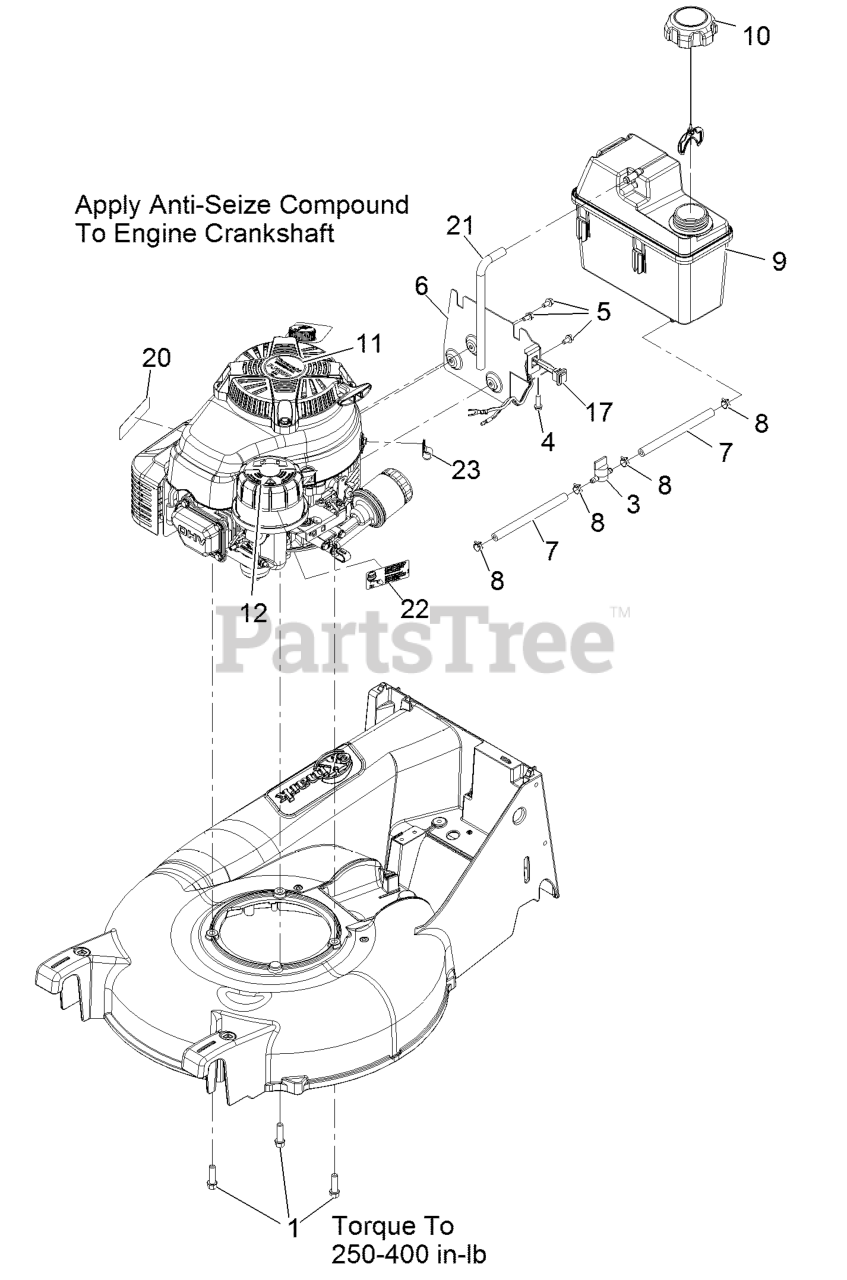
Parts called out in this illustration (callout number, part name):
1	SCREW-TAPTITE
3	VALVE-FUEL
4	SCREW-HWH
5	SCREW-HWH
6	BRACKET,FUEL TANK
7	HOSE-FUEL
8	CLAMP-HOSE
9	TANK-FUEL
17	HARNESS,RUN/STOP
20	DECAL-ARRESTER, SPARK
21	HOSE-VENT, CANISTER
22	DECAL, PRIMER
23	CLIP-LOOM
